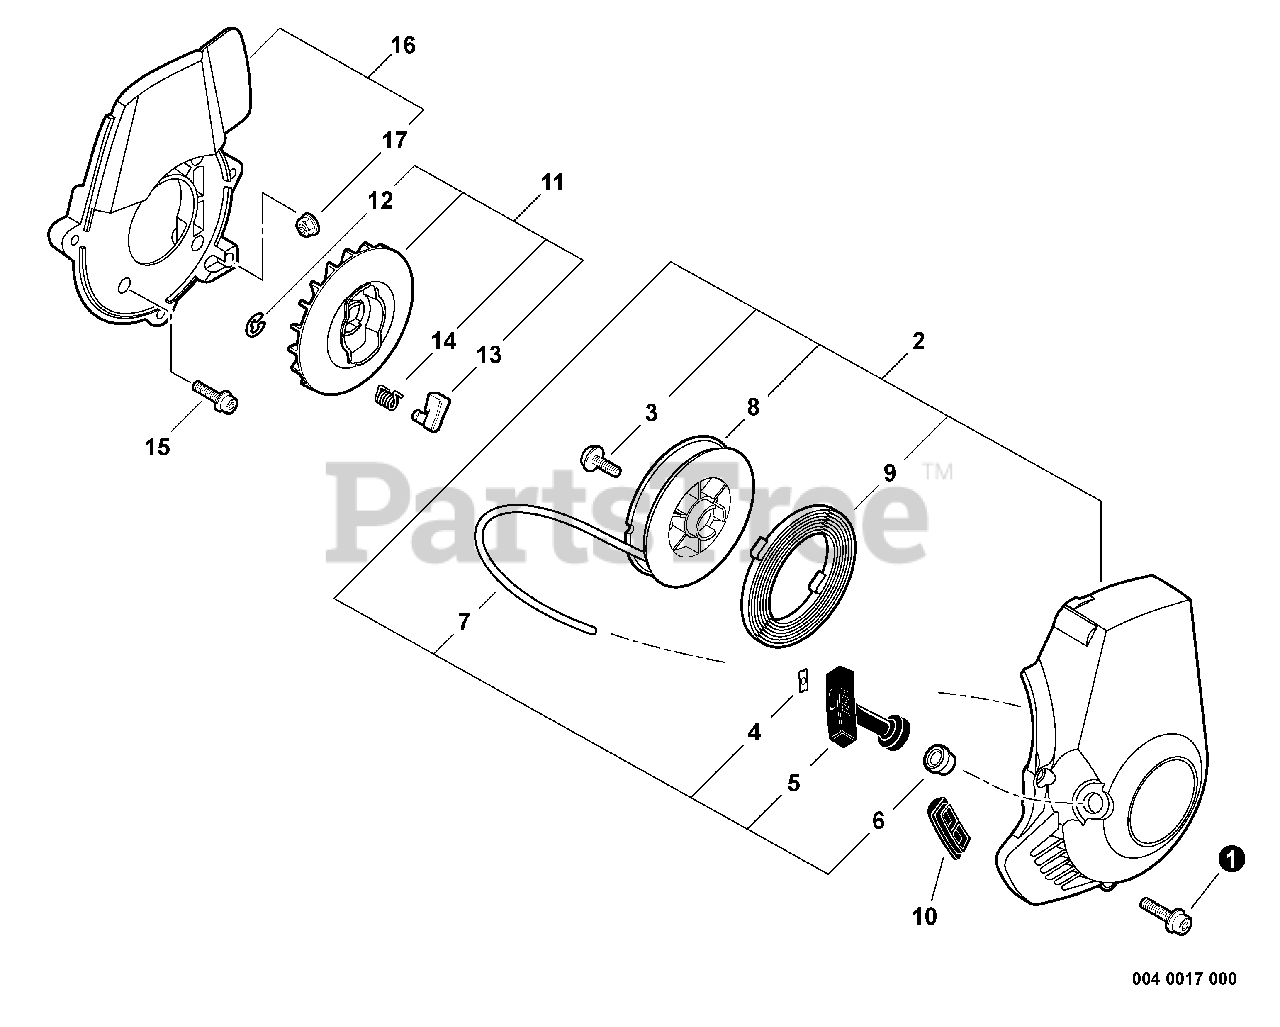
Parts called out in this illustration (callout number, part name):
1	SCREW - 5X14
2	STARTER ASSY
4	RETAINER, ROPE
5	GRIP, STARTER
6	GUIDE, ROPE
7	ROPE, STARTER - 3X700
8	REEL, ROPE
9	SPRING, REWIND
10	CUSHION
11	STARTER PAWL ASSY
12	RING, RETAINING - 4
13	PAWL, STARTER
14	SPRING, RETURN
15	SCREW - 4X16
16	SPACER ASSY
17	NUT - 5 -- FLANGE
